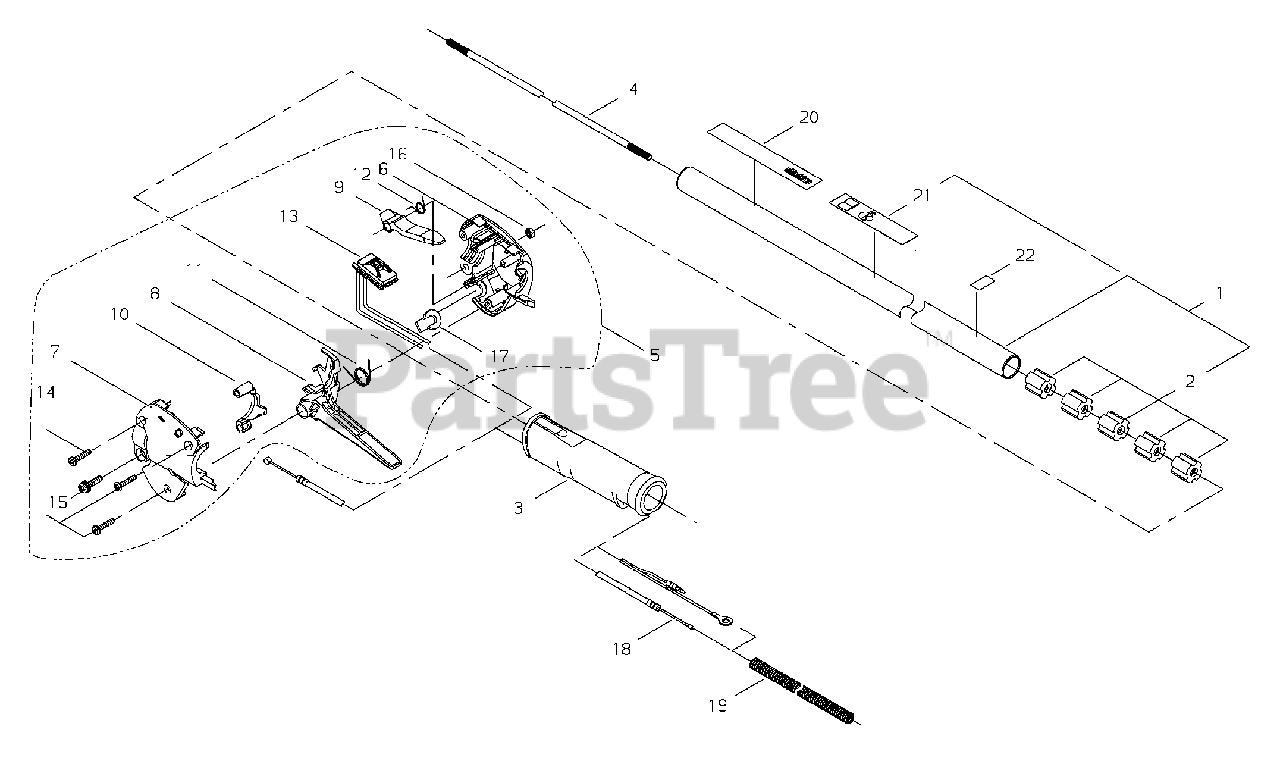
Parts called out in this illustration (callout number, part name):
1	MAIN PIPE ASSY
2	BUSHING
3	GRIP
4	MAINSHAFT
5	THROTTLE LEVER ASSY
6	CONTROL HANDLE - RIGHT
7	CONTROL HANDLE - LEFT
8	TRIGGER, THROTTLE
9	LEVER, THROTTLE LOCKOUT
10	LOCKOUT, THROTTLE
11	SPRING, THROTTLE RETURN
12	SPRING, THROTTLE LOCKOUT
13	SWITCH
14	SCREW, TAPPING M4×20
15	SCREW M5×20
16	NUT M5
17	PLUG
18	CABLE, THROTTLE
19	TUBE, PLASTIC PROTECTIVE
20	LABEL, SHINDAIWA PROFESSIONAL
21	LABEL, CAUTION (NON-BLADE CAPABLE)
22	LABEL, HANDLE
